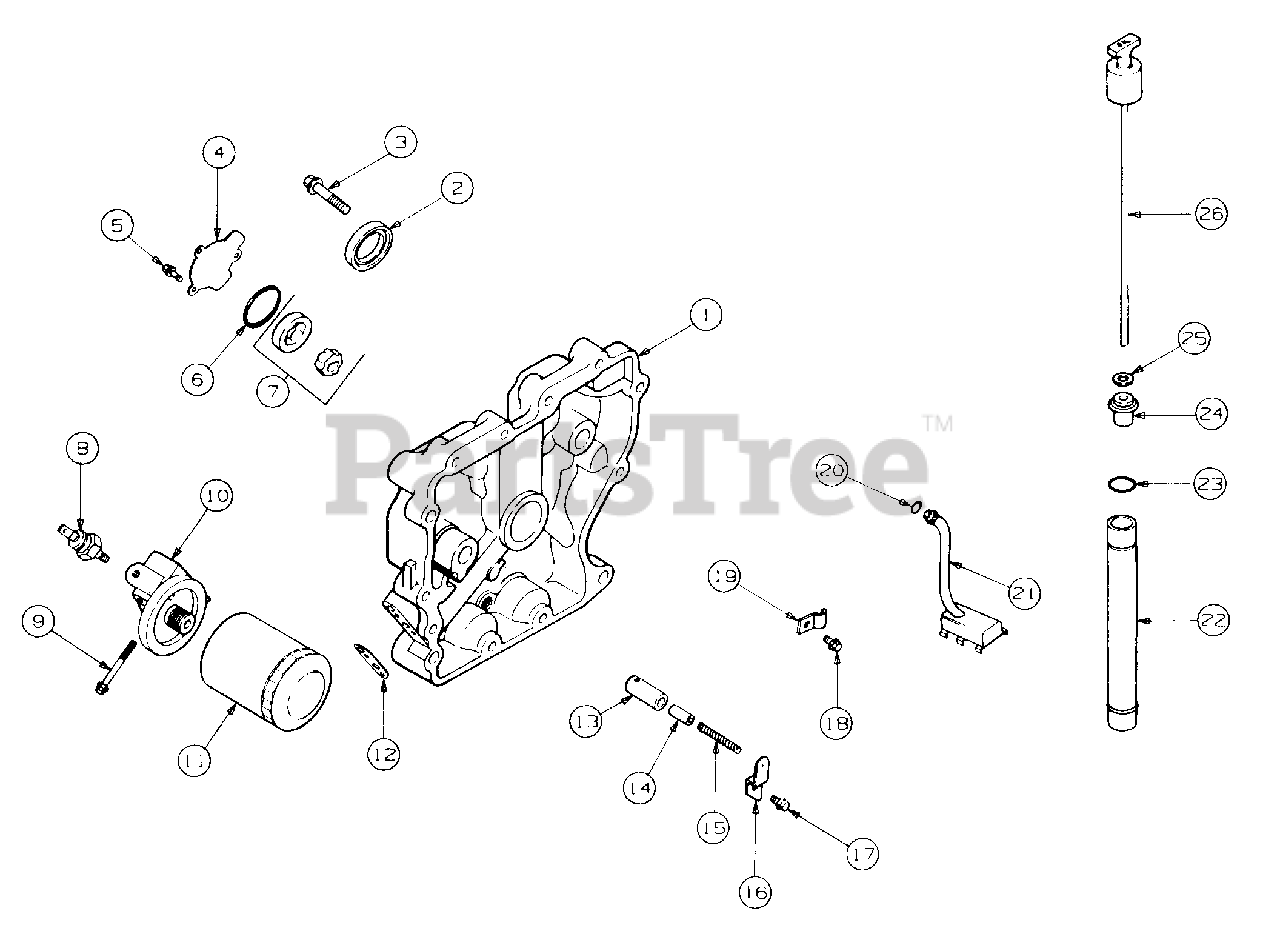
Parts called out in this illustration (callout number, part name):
1	Plate, Closure
2	Seal, Oil (PTO end)
3	Screw, Closure Plate M8 x 1.25 x 45
4	Cover, Oil Pump
5	Screw, Oil Pump Cover, M5 x 0.8 x 16
6	O-Ring, Oil Pump
8	Switch, Oil Pressure
9	Screw, Oil Filter Adapter, M6 x 1.0 x 55
10	Adapter, Oil Filter
11	Filter, Oil
12	Gasket, Oil Filter Adapter
13	Body, Oil Pump Relief Valve
14	Piston, Oil Pump Relief Valve
15	Spring, Oil Pump Relief Valve
16	Bracket, Oil Pump Relief Valve
17	Screw, Screen Cover M5 x 0.8 x 16
18	Screw, Oil Pick-Up M5 x 0.8 x 16
19	Clip, Oil Tube
20	O-Ring, Oil Pick-Up
21	Oil Pick-Up Assy
22	Tube, Oil Fill
23	O-Ring, Lower Oil Fill Tube
24	Seal, Rubber
25	Washer, Plain, 5/16
26	Dipstick Assy
